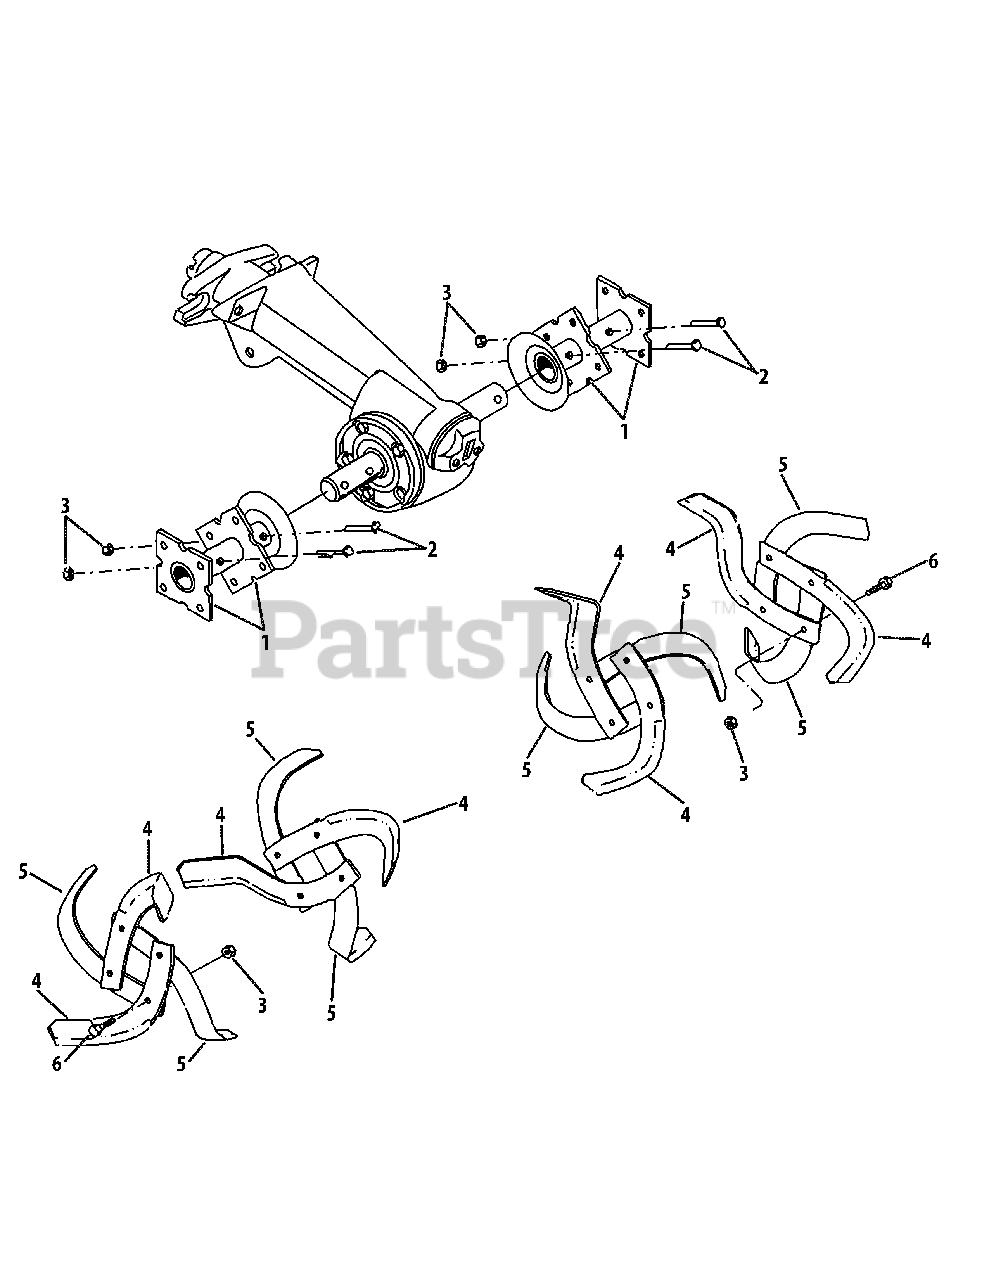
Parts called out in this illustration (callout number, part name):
2	Hex Bolt, 3/8-16 x 2"
3	Hex Locknut, 3/8 "-16
6	Hex Bolt, 3/8 -16 x 1"
